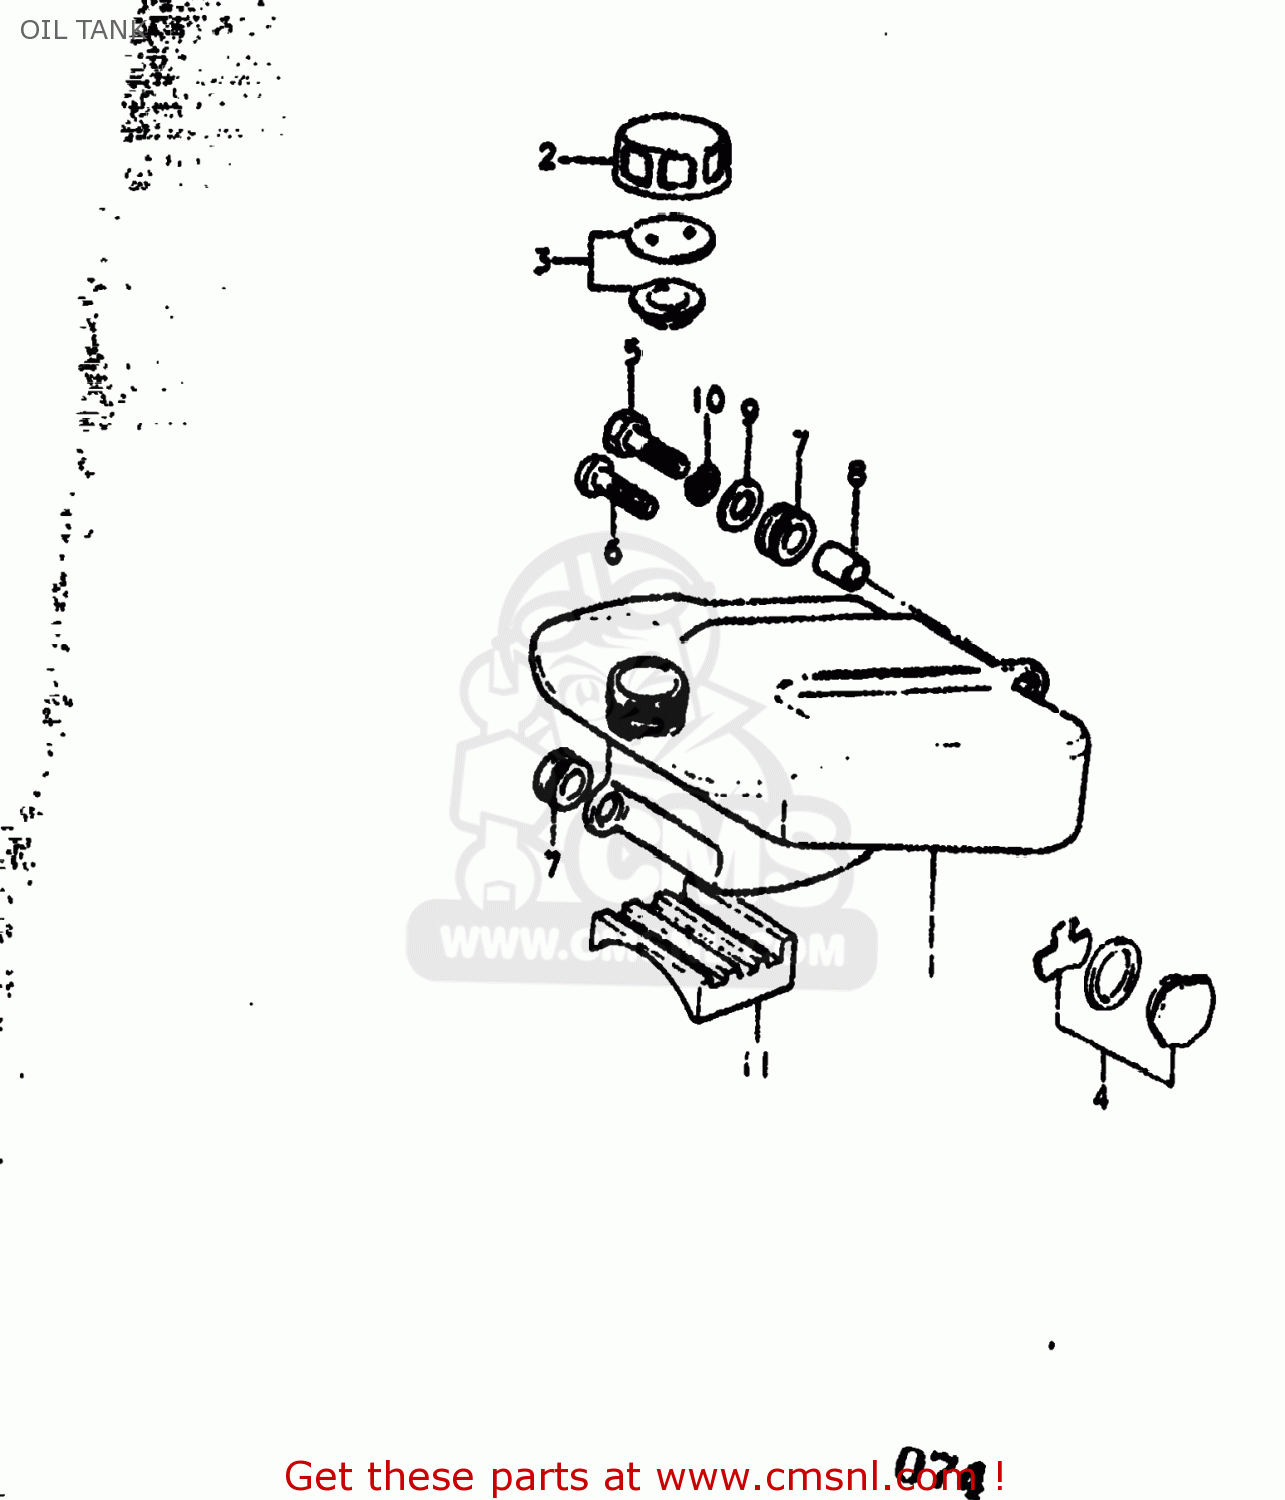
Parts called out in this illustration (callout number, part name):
1	TANK,OIL
2	CAP,OIL TANK
3	LENS,OIL LEVEL INSPECTION
4	LENS,OIL LEVEL INSPECTION
5	BOLT
6	SCREW
7	CUSHION
8	SPACER (6.8X10X10)
9	WASHER
10	LOCK WASHER
11	CUSHION,OIL TANK
